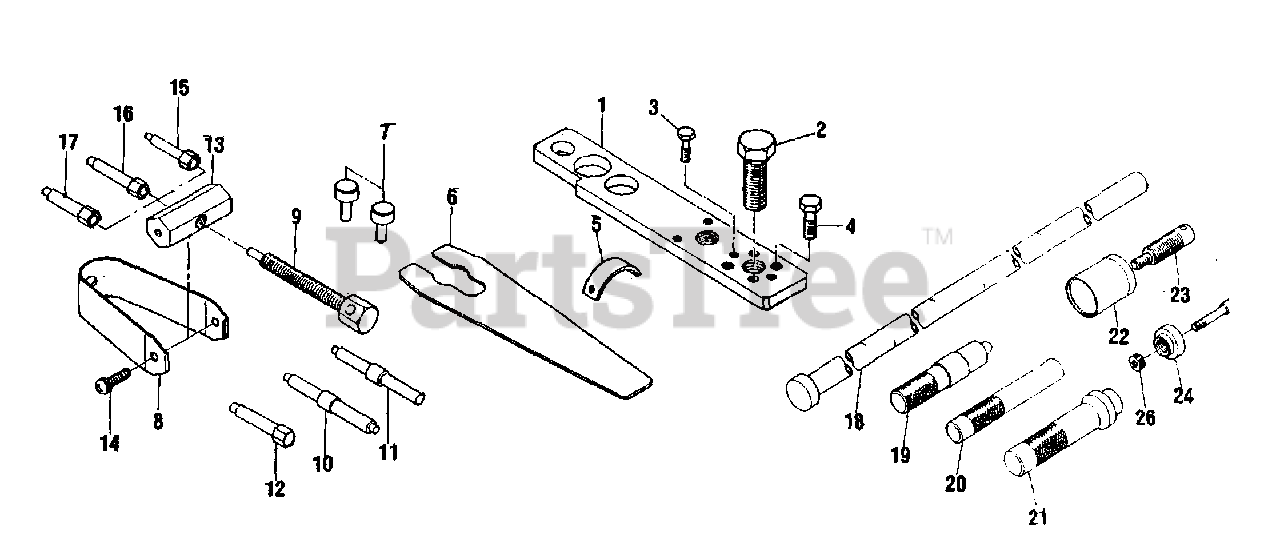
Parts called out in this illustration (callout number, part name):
2	BOLT, CENTER
3	BOLT
4	BOLT
5	AIR GAP GAUGE
6	SPANNER, ROTOR
7	STOPPER
9	BOLT
10	GUIDE PIN
11	GUIDE PIN
12	GUIDE PIN
13	BOSS
14	SCREW - 6X12
15	PIN - ADAPTOR
16	PIN - ADAPTOR
17	PIN - ADAPTOR
18	BUSHING DRIVER
19	BEARING DRIVER (6000 DDU)
20	BEARING DRIVER (6001 ZZ)
21	BEARING DRIVER (6202)
22	HOLDER
23	PULLER BOLT
24	HOLDER
